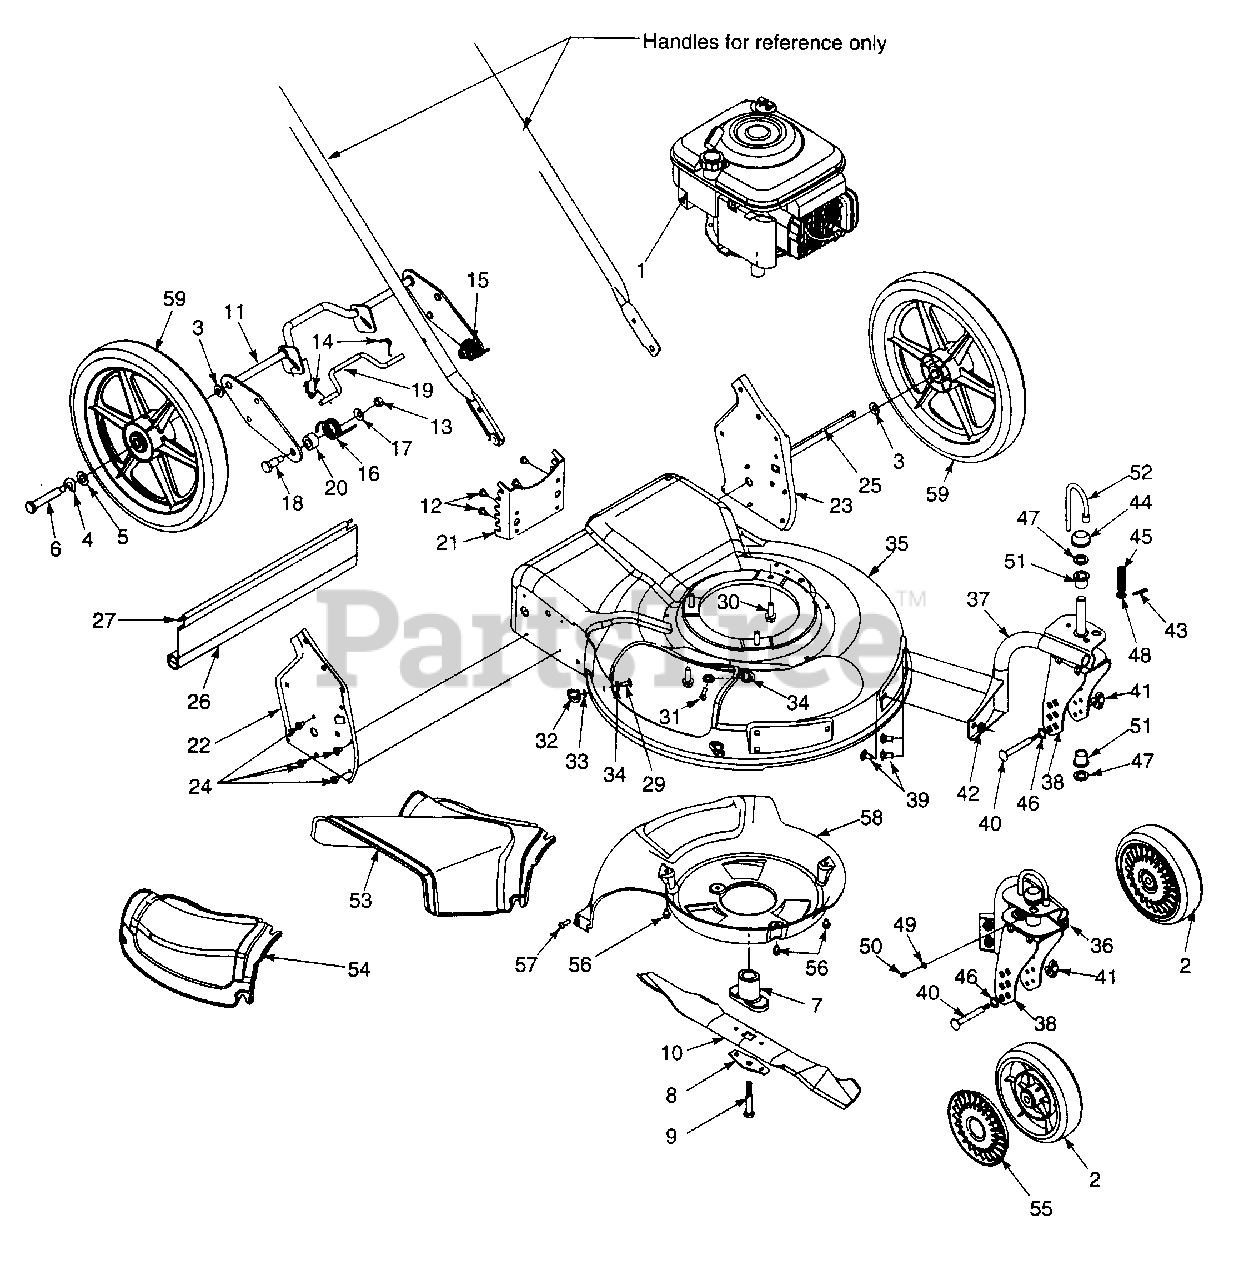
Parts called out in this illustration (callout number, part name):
1	Engine
2	Wheel, Front Caster 7 X 2
3	Bell Washer .401 X .870 X .063
4	Spring Washer.50 I.D. x 1.0 O.D. x.022
5	Flat Washer .510 x 1.0 x .060
6	Shoulder Screw .500 x 2.62: 3/8-16
7	Blade Adapter
8	Blade Bell Support
9	Hex Bolt 3/8 - 24 x 2.5 Gr. 8
10	Blade 21", Mulching
11	Hi-wheel Height Adj. Support
12	AB Screw 1/4-14 x .50
13	Hex Nut 3/8-16
14	Torsion Spring
15	Torsion Spring, RH
16	Torsion Spring, LH
17	Bell Washer .401 x .870 x .063
18	Shoulder Screw .500 x .840
19	Handle, Height Adjustment
20	Spacer .500 x 1.0 x .600
25	Cable Tie
26	Trail Shield
27	Trail Shield Wire
29	Carriage Screw 1/4-20 x .62 Gr. 2
30	TT Screw 3/8-16 x 1.00
31	Carriage Screw 1/4-20 x .75
32	Wing Nut
33	Push Nut
34	Flat Washer
39	Carriage Bolt 5/16-18 x .62
40	Caster Axle .374 x 2.59
41	Wing Nut
42	Flange Nut 5/16-18 Gr.5
43	Hairpin Clip
44	Push Cap
45	Compression Spring
46	Wave Washer .530 I.D. x.780 O.D.
47	Wave Washer .530 I.D. x.780 O.D.
48	Flat Washer .330 I.D. x .630 x .06
49	Fl. Wash. .203 I.D. x .403 x .040
50	Lube Fitting
51	Flange Bearing
52	Lock Pin, Front Wheel
53	Discharge Chute
54	Mulching Cover
55	Hubcap
56	Hex Screw, TT 1/4-20 x .375
57	HL Screw
58	Rear Baffle
59	Hi-Wheel 14 X 2
